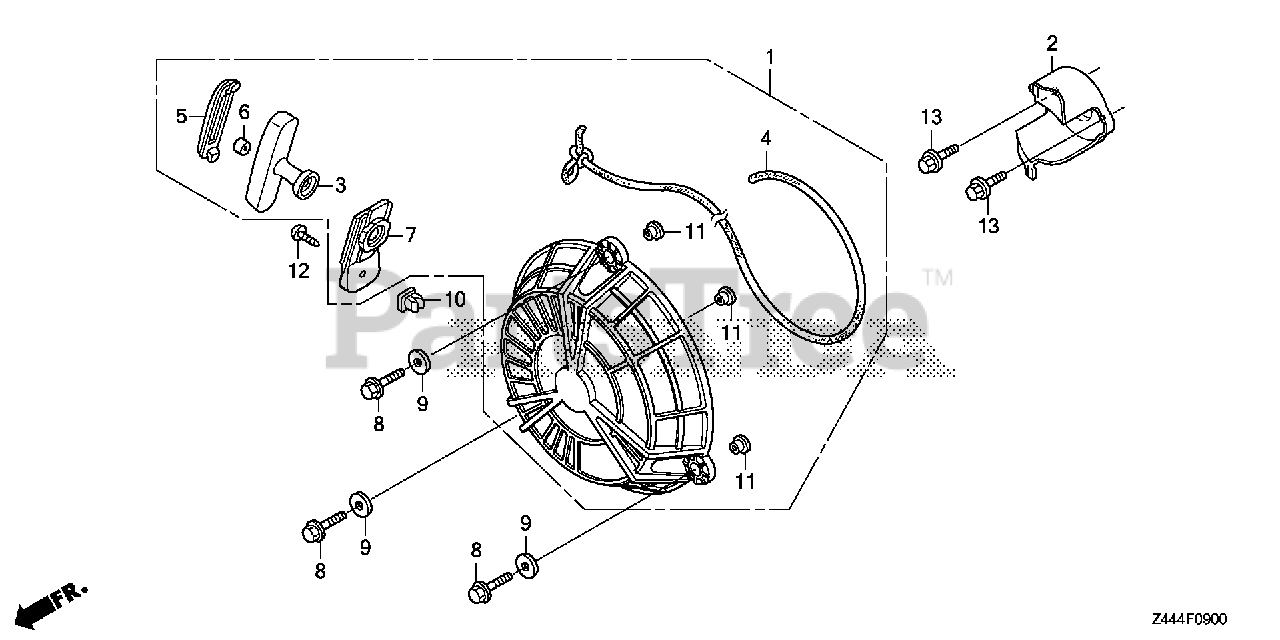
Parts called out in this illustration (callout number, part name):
1	STARTER ASSY., RECOIL
2	PULLEY, STARTER
3	GRIP, STARTER
4	ROPE, STARTER
5	COVER, GRIP
6	GRIP, REINFORCEMENT
7	GUIDE, STARTER ROPE
8	BOLT, FLANGE (6X20) (CT200)
9	WASHER, PLAIN (6.5X15)
10	GROMMET, SCREW (6MM)
11	COLLAR, RECOIL STARTER
12	SCREW, TAPPING (5X16) (PO)
13	BOLT, FLANGE (6X12) Use from Engine SN 2086984.
